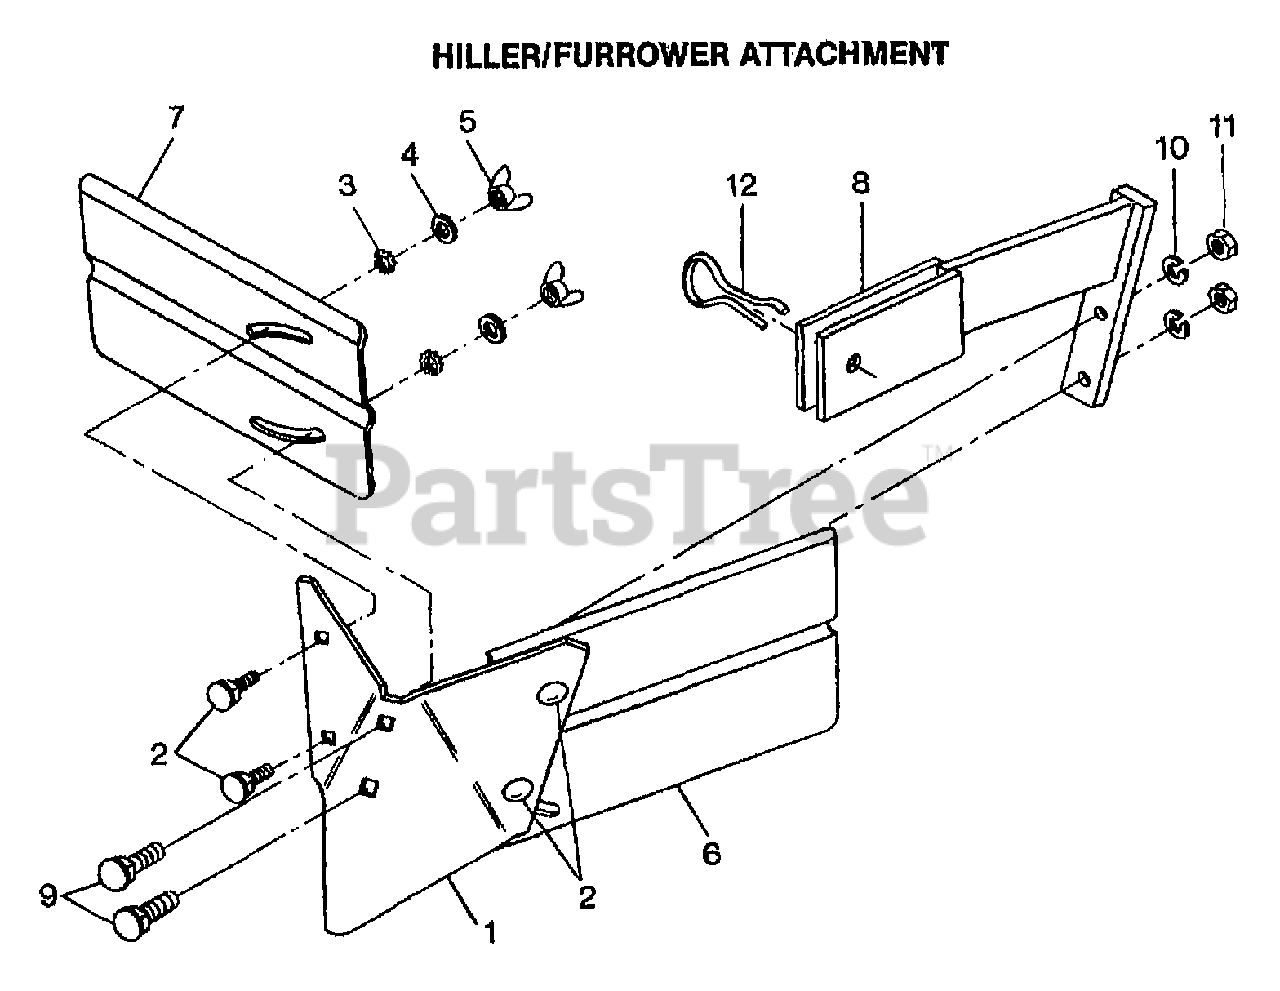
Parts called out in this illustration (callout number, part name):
1	BLADE-FURROWER PNT
2	SCR-CARR 5/16-18X.75 G2 ZP
3	WASHER-LK .312 EXT TOOTH
4	WASHER-FLAT 5/16 SAE
5	NUT-WING/LK 5/16-18 ZP
6	WING-HILLER LEFT PNT
7	WING-HILLER RIGHT PNT
8	BRKT-H/F PNT
9	BOLT-CARR 3/8-16X1.5 ZP
10	WASHER-LK .375 @ DEPL
11	NUT-HEX 3/8-16 ZP
12	PIN-CLINCH .312DIA ZP
